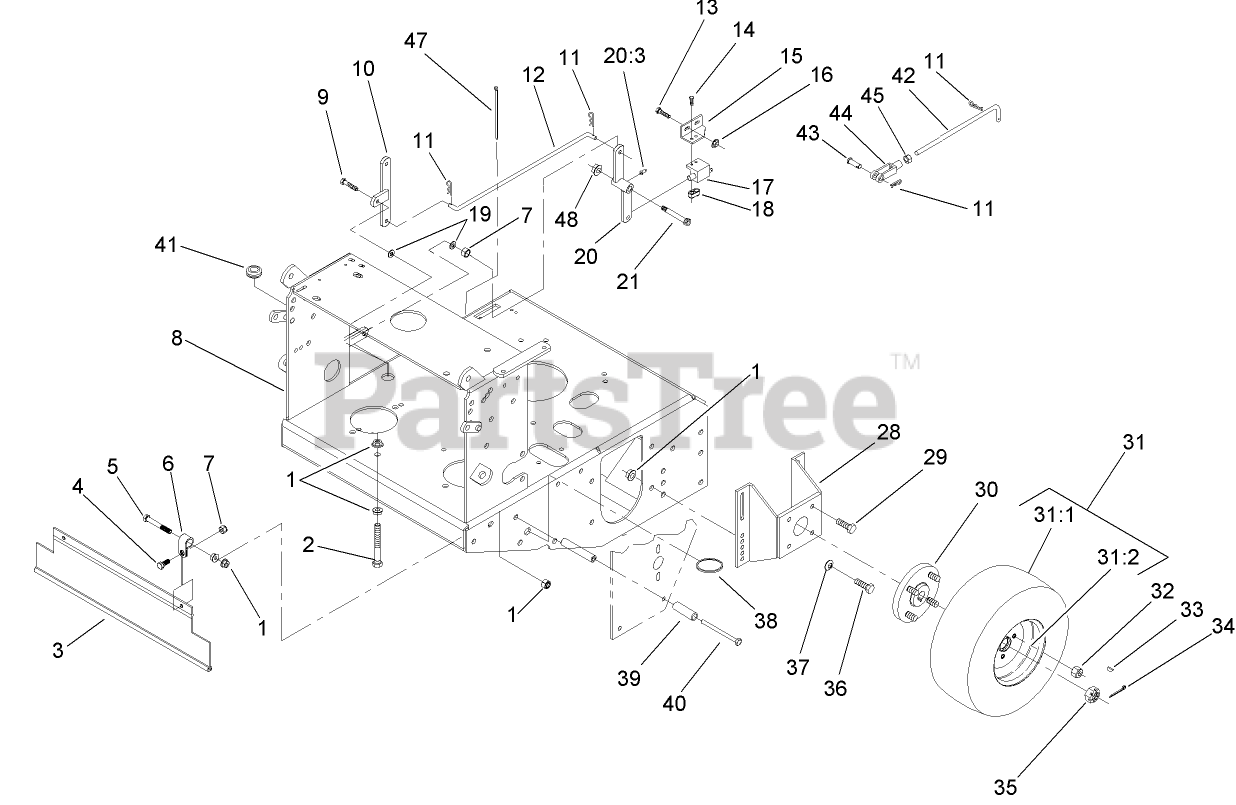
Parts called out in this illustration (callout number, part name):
1	NUT-HHF, WHIZ
2	SCREW-HH
3	Shield-Drag
4	SCREW-HH
5	SCREW-HH
6	Clip-Loom
7	NUT-LOCK, NI
8	HYDRO FRAME ASM
9	SCREW-HH
10	BELLCRANK ASM
11	PIN-COTTER
12	Linkage-Engage, Blade
13	SCREW-HH
14	SCREW-PPH
15	Bracket-Switch, Blade
16	NUT-HF
17	SWITCH-OPEN, NORMALLY
18	PLATE-TAPPED
19	WASHER-PLAIN
20	Bellcrank ASM
20:3	FITTING-GREASE, 90 DEG
28	MOUNT-MOTOR
29	SCREW-HHF
30	HUB ASM W/STUDS
31	WHEEL AND TIRE ASM
31:1	TIRE-TURFMASTER
31:2	Wheel-Rim
32	NUT-LUG
33	Key-Woodruff
34	PIN-COTTER
35	NUT-HEX, SLOTTED
36	SCREW-HH
37	WASHER-BELLEVILLE
38	Ring-Split
39	SPACER-SHORT
40	SCREW-HH
41	GROMMET
42	ARM-LINKAGE, ASSIST
43	PIN-CLEVIS
44	YOKE-ADJUSTABLE
45	NUT-HEX
47	TIE-CABLE
48	NUT-HF
